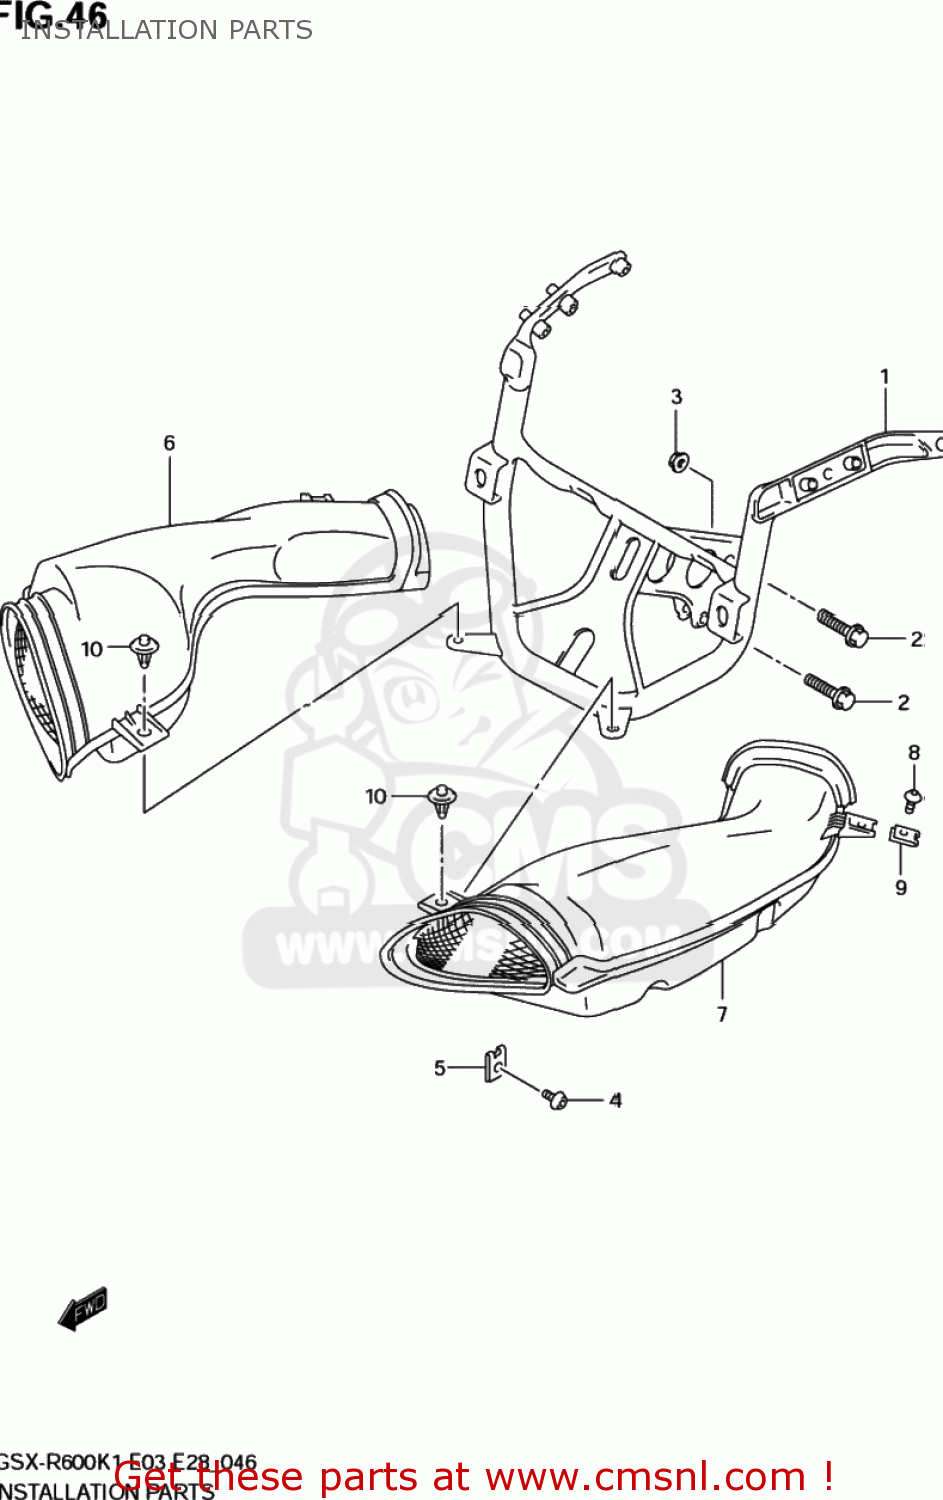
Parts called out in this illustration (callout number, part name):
1	BRACE,COWLING
2	BOLT
3	NUT
4	SCREW(5X13)
5	NUT,COWL
6	PIPE COMP,AIR
7	PIPE COMP,AIR
8	SCREW(5X13)
9	NUT,COWL
10	CLIP
